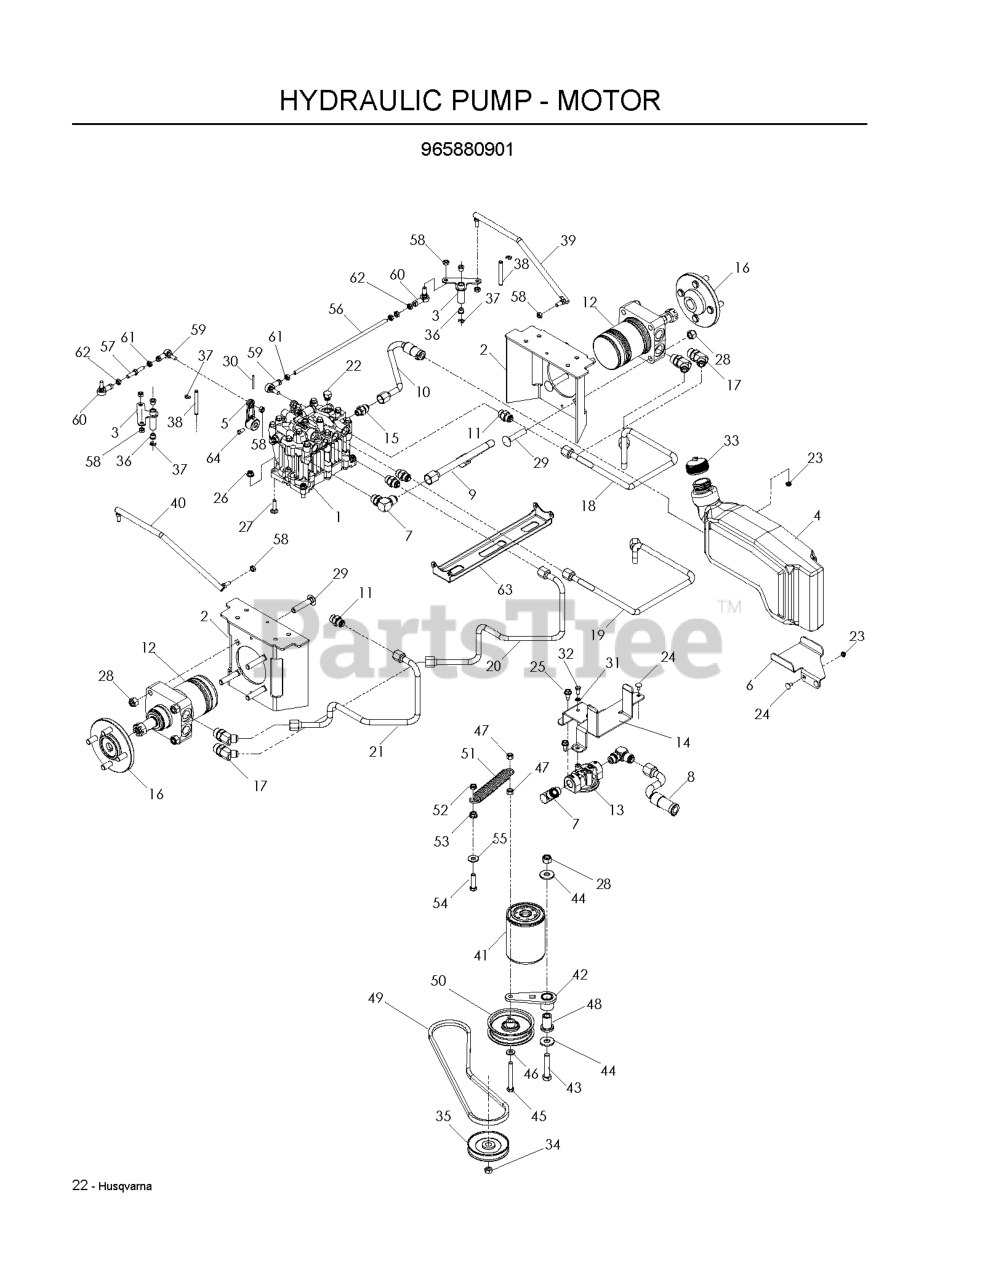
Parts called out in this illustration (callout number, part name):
1	PUMP, DUP10S (77808041201)
2	MOUNT WHEEL MTR BLK
3	ASM MOTN BELLCRK
4	RESERVOIR, HYDRAULIC
6	HOLD LIST SUP RESERVIOR FT-BLK
8	LINE, HYD, SUCTION
9	LINE, HYD, CHARGE
10	LINE, HYD, CASE
11	FITTING, STRAIGHT F6400-8-8-0
12	WHEEL MOTOR
13	FILTER HEAD
14	HOLD LIST SUP RESERVOIR RR-BLK
15	FITTING, HYDRO
16	HUB.WHEEL.ZTR
17	ELBOW-ADJ 45 DEG F6802-8-10
18	LINE, HYD, D
19	LINE, HYD, C
20	LINE, HYD, B
21	LINE, HYD, A
22	PLUG, 6408-6
23	JAM NUT 1/4C (2 2 PW01)
24	RHSSNB 1/4-20 X 1/2
25	BOLT 5/16-18 X 3/4
26	5/16-18 NYLOC FLANGE NUT
27	BOLT, CARRIAGE 5/16X1-1/4
28	NUT 1/2-13 HEX NYLOC ZD
29	RHSNB 1/2 - 13 X 2 - 1/2 GR5
30	PIN, SPIRAL, 5/32 X 1 1/2
31	LOCKWASHER 1/4"
32	HCS 1/4C X 5/8
33	HYDRAULIC CAP
34	NUT M10-1.5 L/H HEX
35	PULLEY, PUMP
36	BUSHING, BAIL 5/16
37	RING RETAINING EXT 5/16
38	PIN, MOTION
39	LINK MTN CTL, FT-LT
40	LINK MTN CTL FT-RT
41	HYDRAULIC OIL FILTER
42	RP.IDLER ARM WELDMENT
43	HEX SCREW 1/2-13 X 2.5" GR 5
44	WASH USS FLAT 1/2
45	TAPBOLT, 3/8C X 3
46	WASHER 3/8 SAE FLAT
47	NUT 3/8-16 NYLOC
48	PIVOT, IDLER
49	BELT, TRANSMISSION
50	PULLEY, IDLER RAKE & ZTR
52	NUT HEX 3/8-16 NYLON, THIN
53	NUT 3/8C WHIZ
54	TAP BOLT 3/8C X 1.5
55	WASHER 3/8 FLAT
56	ASM MTN LINK RR-LT
57	ASM MTN LINK RR-RT
58	NUT 5/16-24 TOP LK GRC ZD
59	SPHERICAL ROD END, RH
60	SPHERICAL ROD END, LH
61	NUT 5/16F LEFTHAND
62	NUT 5/16-24 UNF HEX JAM
63	SUPPORT WHEEL MOTOR BLACK
64	SCREW 5/16C X 5/8 SQ HEAD
